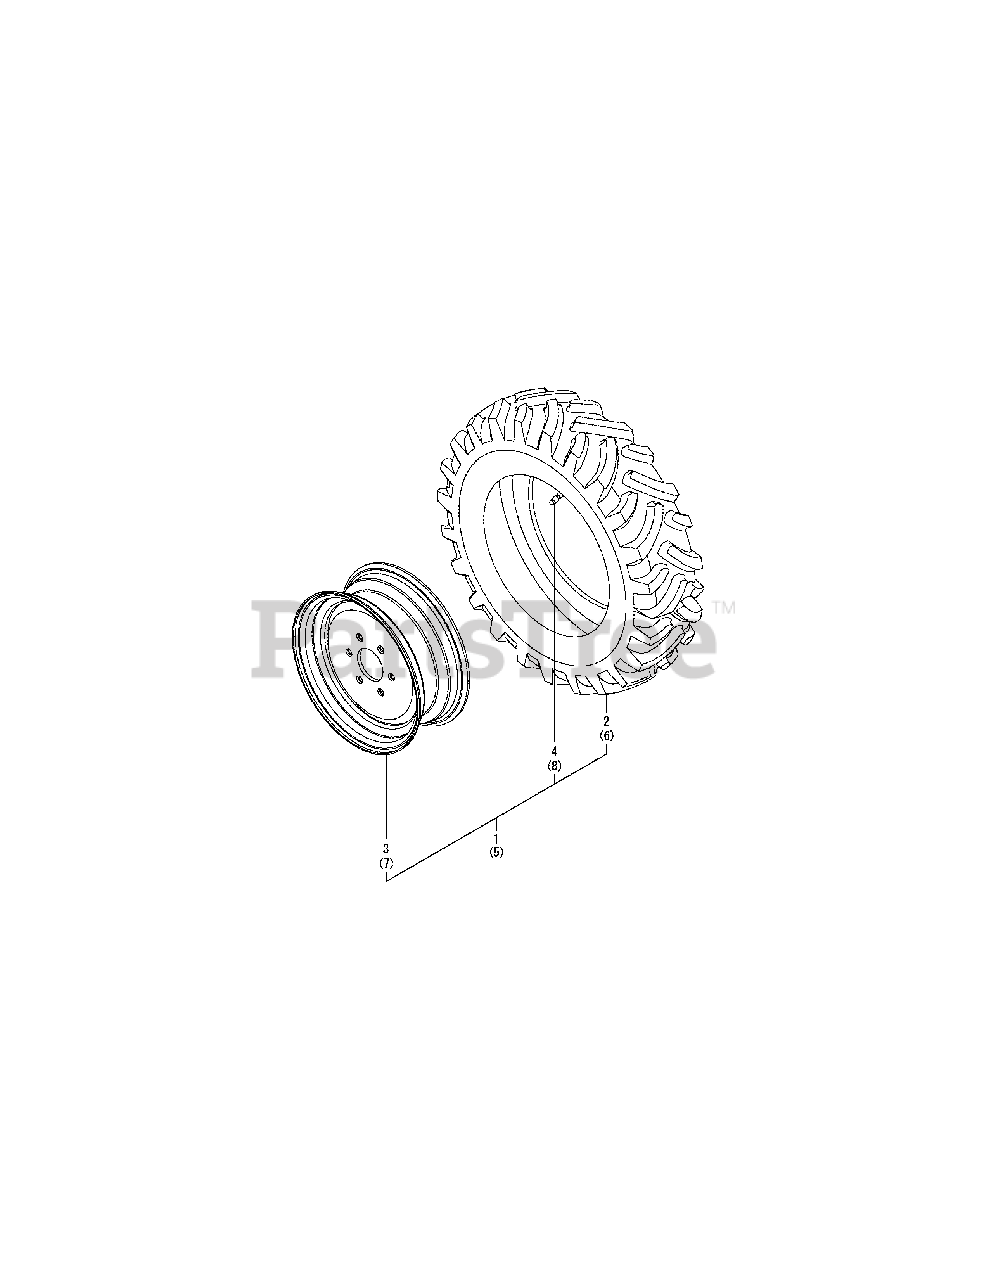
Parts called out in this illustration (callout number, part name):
1	R1 TIRE ASM, FRONT LEFT
2	R1 TIRE 8-16, AG
4	VALVE, FRONT TIRE
5	R1 TIRE ASM, FRONT RIGHT
6	R1 TIRE 8-16, AG
8	VALVE, FRONT TIRE
